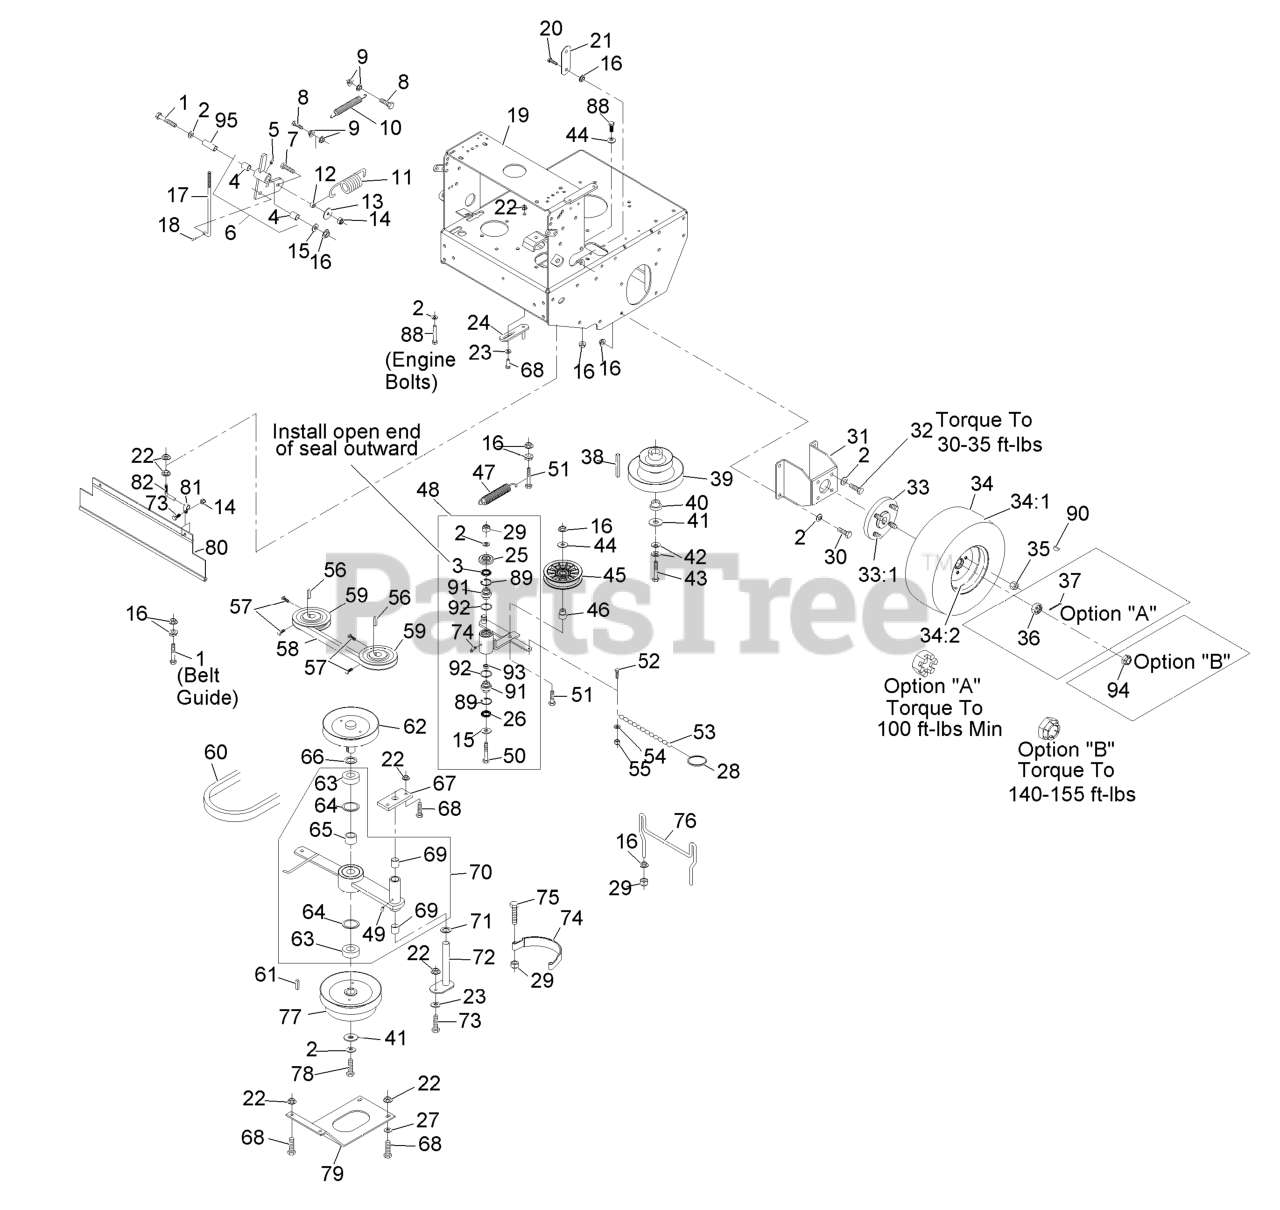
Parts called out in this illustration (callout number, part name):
1	SCREW-HH
2	WASHER-BELLEVILLE
3	SEAL-LIP, SINGLE
4	SLEEVE-BEARING
5	FITTING-GREASE
6	ASM,PIVOT W/BUSHINGS
7	SCREW-HH
8	SCREW-HH
10	SPRING,EXTENSION
11	SPRING,EXTENSION
12	SPACER,CLUTCH ANCHOR
14	NUT-LOCK, NI
15	WASHER-FLAT
16	NUT-HHF, WHIZ
17	LINKAGE,LOWER
18	PIN-COTTER
19	KIT,TTHP ENG DECK
20	SCREW-HH
21	ARM-LIFT, DECK
23	WASHER-SPRING
24	GUIDE-BELT
25	GUARD-TOP
26	SEAL-LIP, DOUBLE
27	WASHER-FLAT
28	RING-SPLIT
29	NUT-LOCK, NI
30	SCREW-HH
31	WLD,MOTOR MOUNT 48&52
32	SCREW-HH
33:1	STUD-WHEEL
34	WHEEL AND TIRE ASM
34:1	TIRE-TURFMASTER
34:2	RIM-WHEEL
35	NUT-LUG
36	NUT-HEX, SLOTTED
37	PIN-COTTER
38	KEY,MACH 1/4X1/4X2-5/8
39	SHEAVE, DRIVE
40	BUSHING,CLUTCH KEEPER
42	WASHER-SPRING
43	SCREW-HH
44	WASHER-FLAT
45	PULLEY-IDLER, FLAT
46	BUSHING-IDLER
48	KIT,PUMP IDLER ARM TTHP
49	FITTING-GREASE
50	SCREW-HH
51	SCREW-HH
52	SCREW-HSH
53	CHAIN-LINK, TWIST
54	WASHER-FLAT
55	NUT-LOCK, NI
57	SCREW-SET
58	BELT,COG A 50.55
59	SHEAVE ASM
60	BELT,B-38.0
62	SHEAVE, W/ SHAFT
63	BEARING,CLUTCH SHAFT
64	RING-SNAP
65	SPACER,CLUTCH BEARING
66	WASHER-SPACER
67	PLATE-CLUTCH PIVOT
68	SCREW-HH
69	SLEEVE,BEARING
70	ASM,CLUTCH ARM W/BEARING
71	WASHER-SPACER
72	WLD,PIN PIVOT
73	SCREW-HH
74	BAND,BRAKE BLADE
75	SCREW-HH
76	GUIDE,BELT (PLTD)
77	SHEAVE,6.75 W/DRUM
78	SCRW,CAP HH
79	PLATE-GUARD
80	SHIELD-DRAG
81	CLIP-LOOM
82	MOUNT,DRAG SHIELD
88	SCREW-HH
89	RING-SNAP
90	KEY-WOODRUFF
91	BEARING-SPHERICAL
94	NUT-LOCK
95	BUSHING
